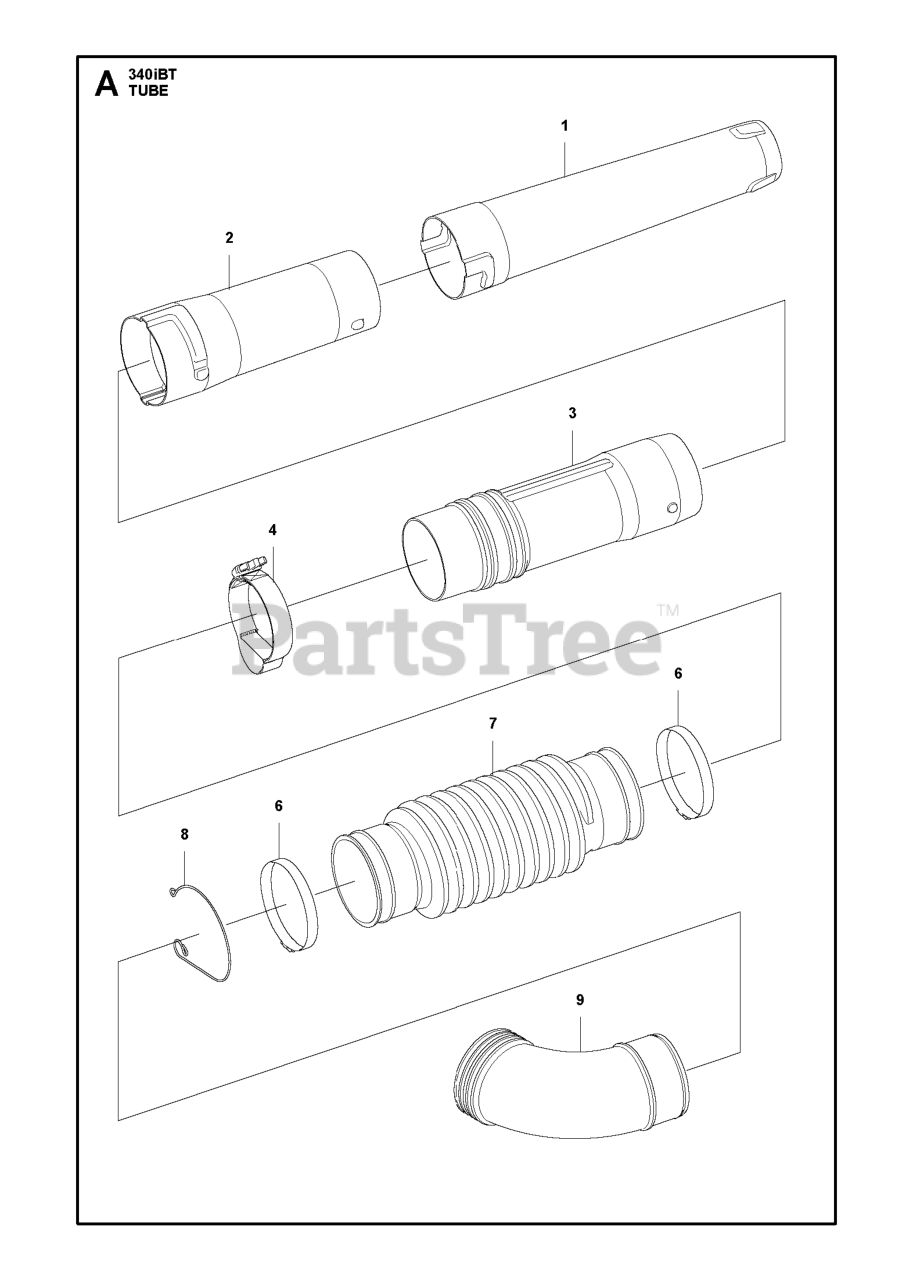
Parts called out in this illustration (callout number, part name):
1	NOZZLE BLOWER 320IB
1	SLEEVE TUBE
2	TUBE ADAPTER PLASTIC HUSQVARNA
2	SCREW ITXSCT MT5X16 10.9 TBO
2	HANDLEBAR ASSY
3	SWIVEL JOINT
4	STRAP TUBE BLOWERS
4	TUBE ASSY NOZZLE SILENCER
5	BLOWER NOZZLE FOR 320IB
6	CLAMP(F115)
7	HOSE FLEXIBLE
7	TUBE ASSY NOZZLE 536LIBX
9	PIPE ELBOW
9	NOZZLE FLAT
10	PIPE STRAIGHT
